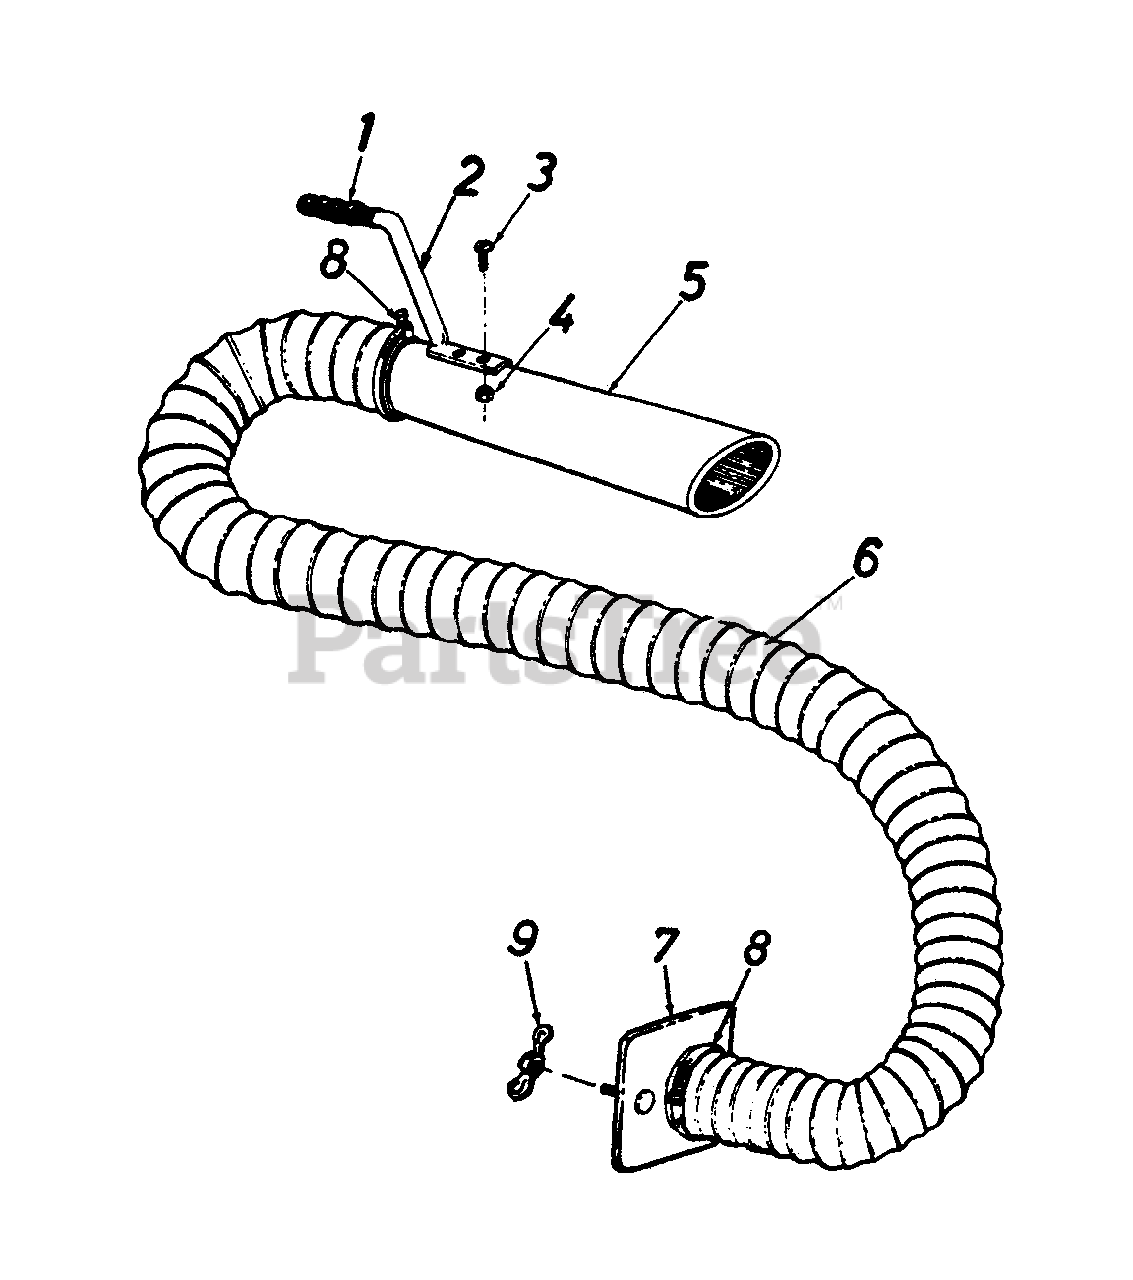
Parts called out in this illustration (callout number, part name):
1	Handle Grip
4	Hex Nut 10-24 Thd.
5	Hose Nozzle
6	Flexible Hose 4" Dia. x 10'
7	Hose Adapter Plate
8	Hose Clamp-4"
9	Wing Nut 1/4-20 Thd.
